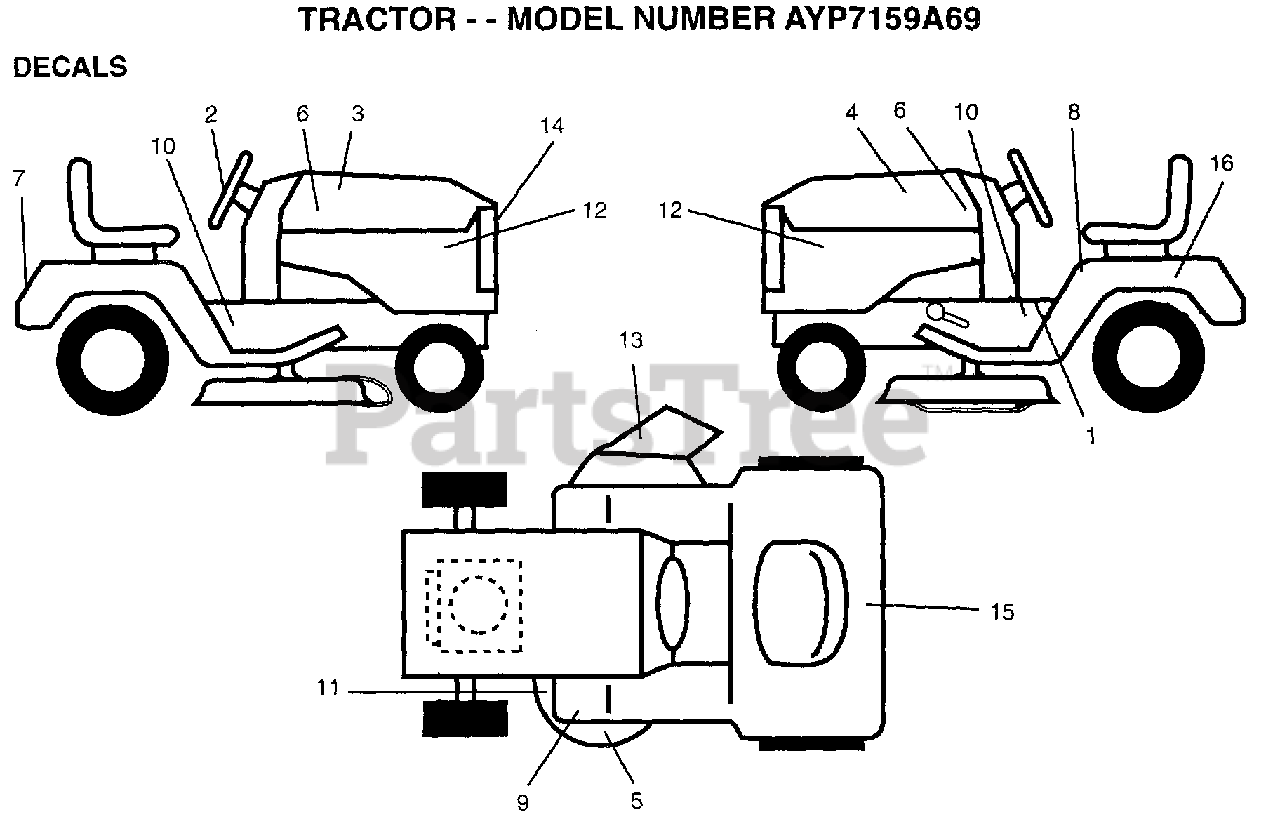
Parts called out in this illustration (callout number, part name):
2	DECAL STEER WHL
3	DECAL HOOD RH
4	DECAL HOOD LH
5	DECAL DECK WIZ +
6	NAMEPLATE.HD.WIZA
8	DECAL
10	DECAL CHASSIS WIZ
11	DECAL
12	DECAL.PNL.SD.VANG
13	DECAL DECK MULCH
14	DECAL.LENS.WIZARD
15	DECAL.BATRY.3-3908
